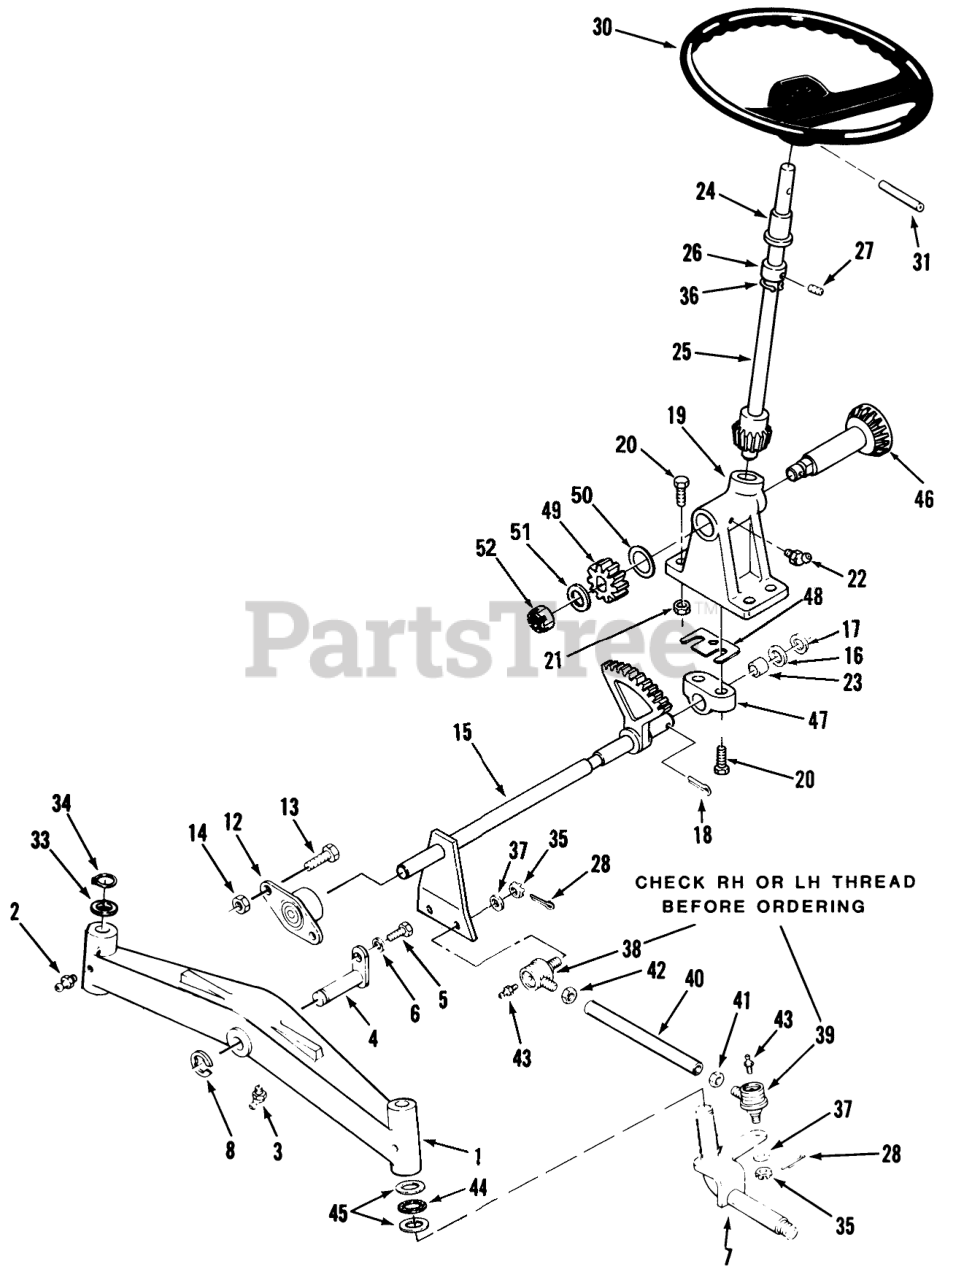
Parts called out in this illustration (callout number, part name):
1	Axle-Front
2	Zerk
3	FITTING-GREASE
4	PIN AND PLATE ASM
5	H H C S
6	WASHER-LOCK
7	Spindle
8	E-RING
12	BEARING-FLANGED
13	SCREW-HH
14	NUT-LOCK, NI
15	Shaft
16	WASHER-SHIM
17	WASHER
18	PIN-COTTER
19	Steering Support
20	Bolt
21	NUT-LOCK, NI
22	ZERK FITTING
23	BLOCK-BEARING
24	BEARING-FLANGED
25	WLDMT-STRG SHAFT
26	COLLAR
27	SCREW-SET
28	TUBE-STEERING
30	Steering Wheel
31	Pin-Roll
33	WASHER
34	Snap Ring
36	RING-RETAINING
37	WASHER
38	SOCKET-BALLJOINT
39	SOCKET-BALLJOINT
40	Tube
41	NUT-HEX JAM 9/16-18
42	Nut
43	Grease Fitting
44	BEARING-THRUST
45	WASHER-THRUST
46	WLDMT-C SHAFT
47	BLOCK-BEARING
48	SHIM-.010
49	PINION-SPUR
50	Washer
51	Washer
52	Nut
